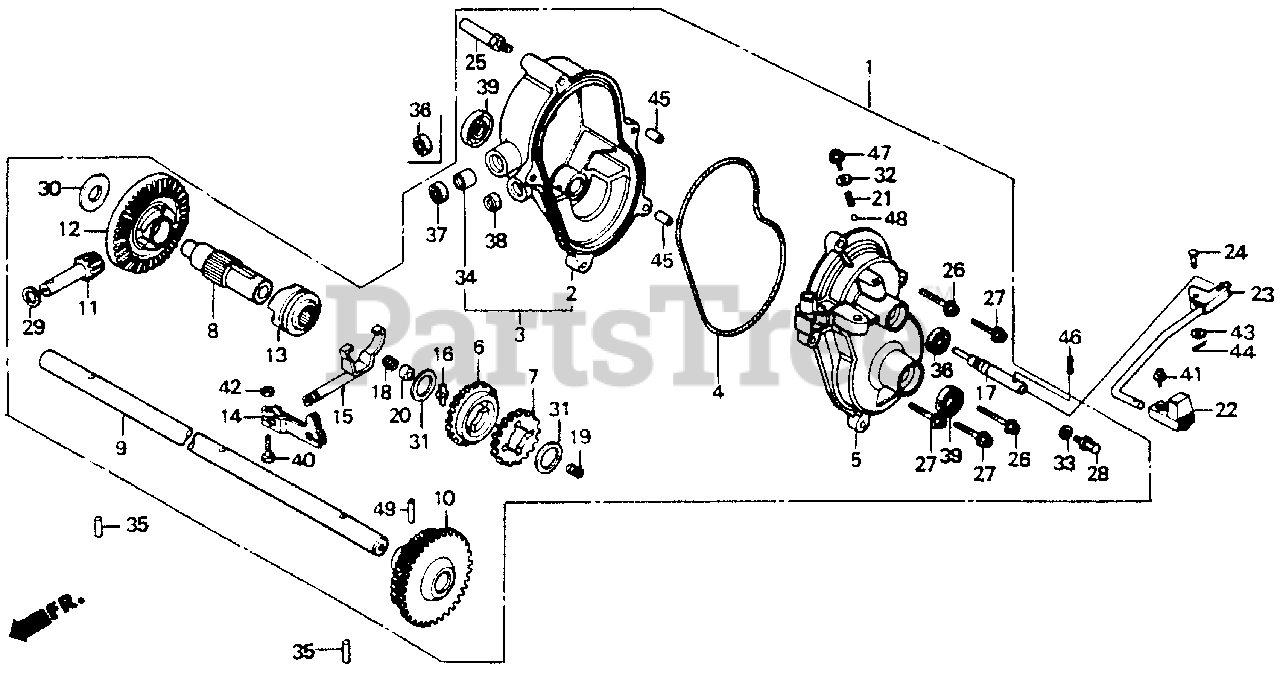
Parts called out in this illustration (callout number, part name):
1	TRANSMISSION ASSY.
3	CASE, R. TRANSMISSION
4	O-RING, TRANSMISSION CASE
5	CASE, L. TRANSMISSION
6	GEAR, HIGH DRIVE (26T)
7	GEAR, LOW DRIVE (22T)
8	COUNTERSHAFT
9	SHAFT, FINAL
10	GEAR, FINAL (38T/42T)
10	GEAR, FINAL
11	PINION, BEVEL
12	GEAR, BEVEL (52T)
13	CLUTCH, DRIVEN
14	ARM, CLUTCH
15	SHAFT, SHIFT
17	SLIDER, SHIFT
18	SPRING, SHIFT
19	SPRING, HIGH GEARSHIFT
20	RETAINER, SHIFT SPRING
21	SPRING, BALL SETTING
22	KNOB, CHANGE LEVER (NOT AVAILABLE)
23	LEVER, CHANGE
24	PIN (8X18)
25	BOLT, GUIDE (8MM)
26	BOLT, FLANGE (6X25)
27	BOLT, FLANGE (6X25)
28	BOLT, DRAIN PLUG
29	WASHER (10X21)
30	WASHER, THRUST (12MM)
31	WASHER, THRUST (16MM)
32	WASHER, SEALING (6.5X12)
33	WASHER, DRAIN PLUG (10.2MM)
34	BEARING, NEEDLE (10X17X20)
35	ROLLER (5X23.8)
36	OIL SEAL (10X20X5)
37	OIL SEAL (10X17X4) (ARAI)
38	OIL SEAL (8X14X5)
39	OIL SEAL (15X24X5)
40	BOLT, HEX. (5X20)
41	SCREW-WASHER (4X12)
42	NUT, HEX. (5MM)
43	WASHER, THRUST (8.1MM)
44	PIN, COTTER (2.0X15)
45	PIN A, DOWEL (8X14)
46	PIN, SPRING (4X20)
47	BOLT, FLANGE (6X10)
48	BALL, STEEL (#6) (3/16)
49	ROLLER (6X22.4)
